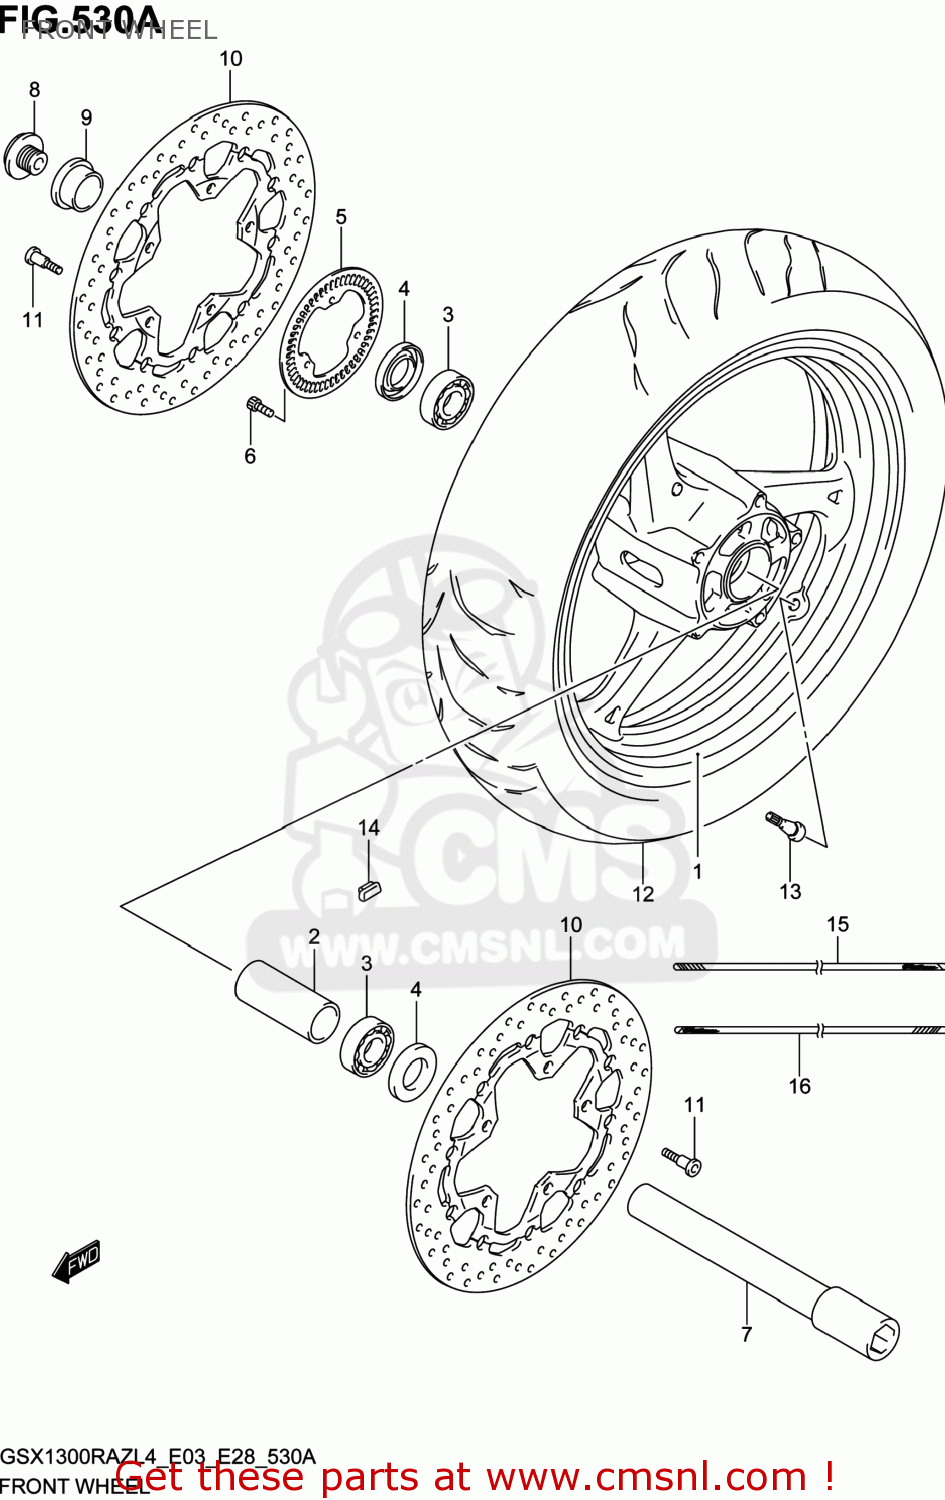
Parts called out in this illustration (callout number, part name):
1	WHEEL,FR(17M/CXMT3.50)
2	SPACER,FR HUB BEARING
3	BEARING(25X52X15)
4	SEAL,OIL(32X52X7)
5	RING,SPEED SENSOR FR(50T)
6	BOLT
7	AXLE,FR
8	BOLT,FR AXLE
9	SPACER,FR AXLE,R
10	DISC,FR BRAKE
11	BOLT(8X21)
12	TIRE,FR
13	VALVE ASSY,WHEEL RIM(TR412)
14	BALANCER,WHEEL(10G)
15	TAPE,WHEEL FRONT,R
16	TAPE,WHEEL FRONT,L
